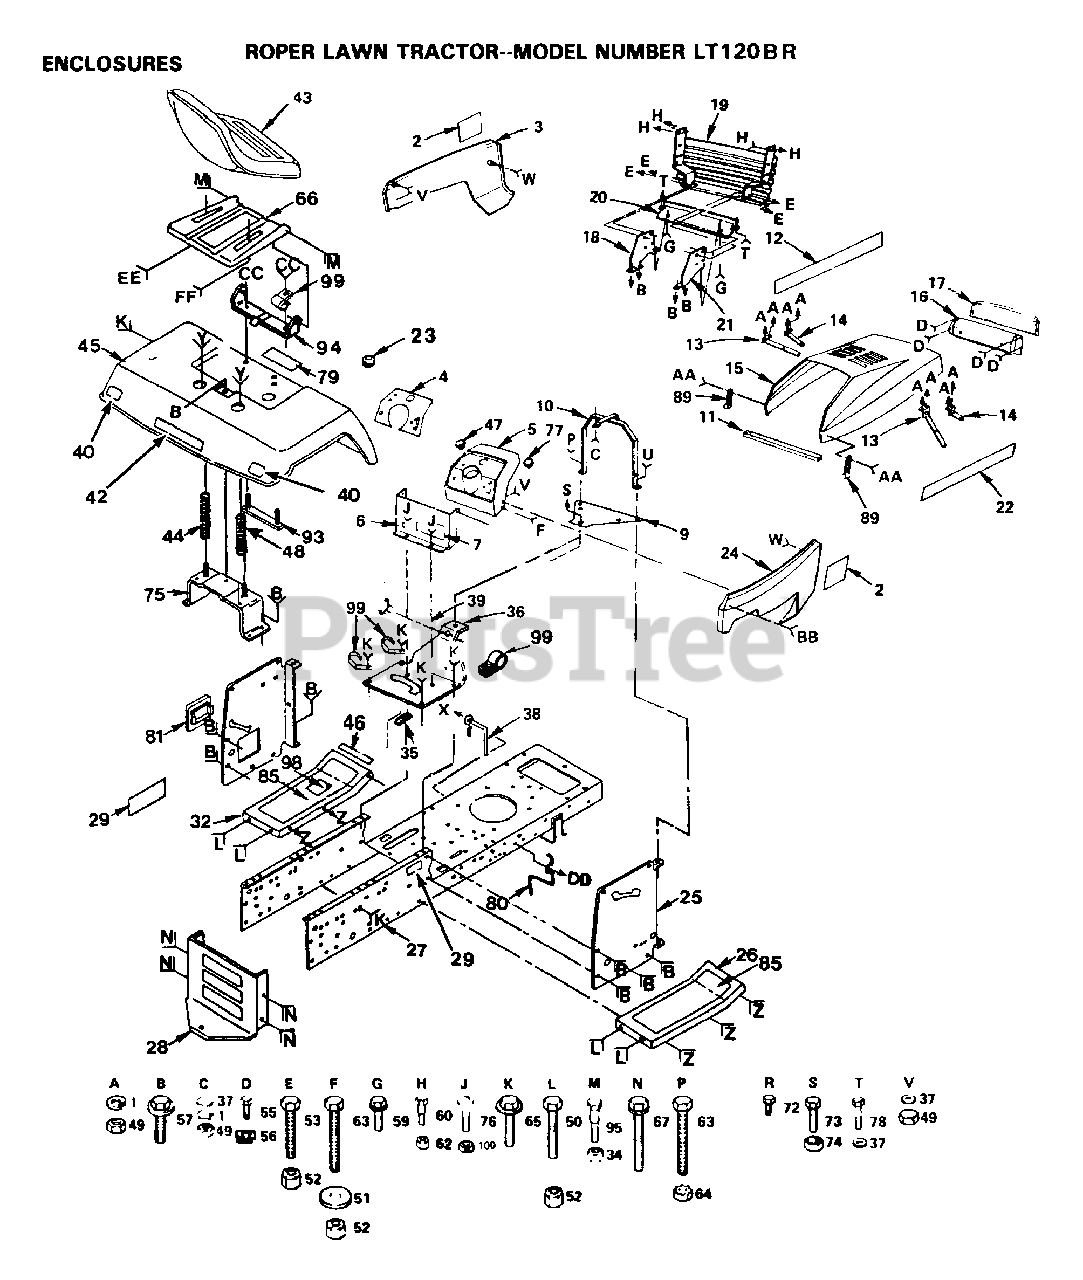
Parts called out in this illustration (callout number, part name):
6	DASH ASSY LT
10	SUPPORT ASSY LT
11	FOAM-STRIP LT
17	LENS LT
18	SUPPORT-GRILL LT
23	GROMMET T
25	PANEL DASH RH YT
32	FOOTREST LH YT
37	WASHER PM
40	REFLECTOR-TAIL YT
47	PLUG-DASH T
53	BOLT
56	"""J"" FASTENER LT"
57	SCREW
59	SCREW
60	BOLT T
65	SCREW LT
67	SCREW
73	BOLT
76	SCREW
77	PLUG BUTTON T
78	SCREW HEX CRT
89	HOOD LATCH T
99	CLIP T
